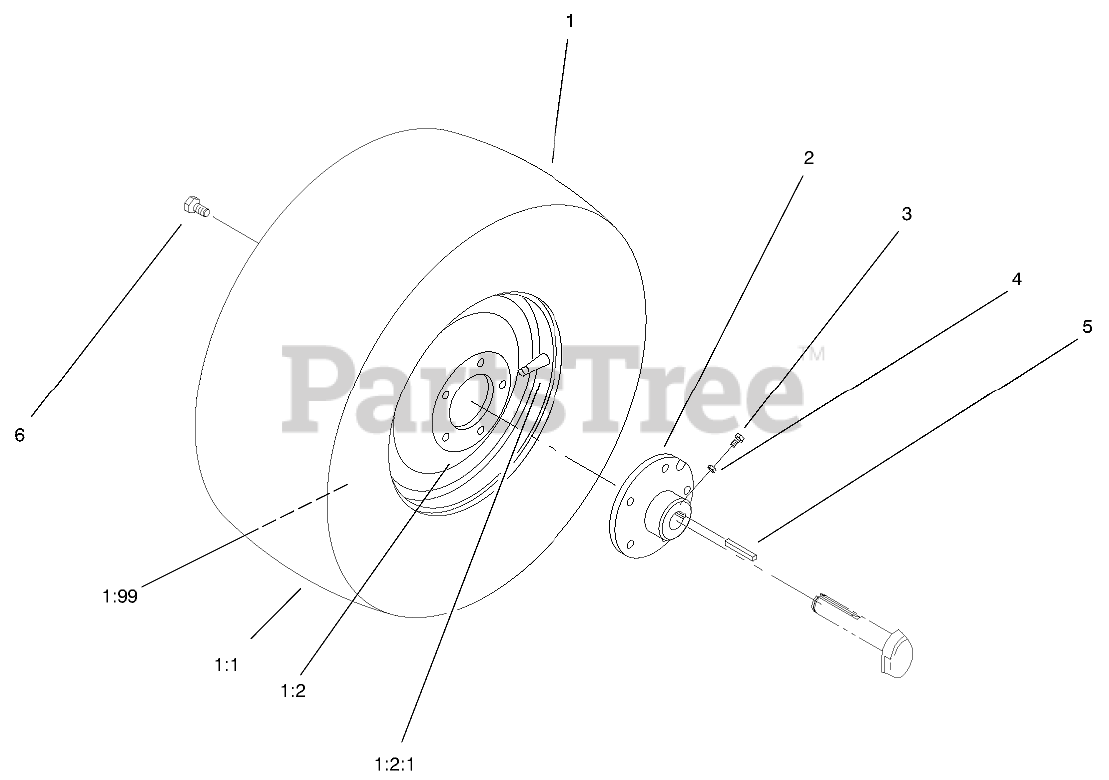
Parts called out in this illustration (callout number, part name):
1	Wheel&tire ASM,Rear
1:2	WHEEL
1:2:1	VALVE
1:99	TUBE-INNER
2	HUB-WHEEL
3	SCREW-SET, SQH
4	NUT-JAM
5	KEY-SQUARE
6	BOLT-LUG
